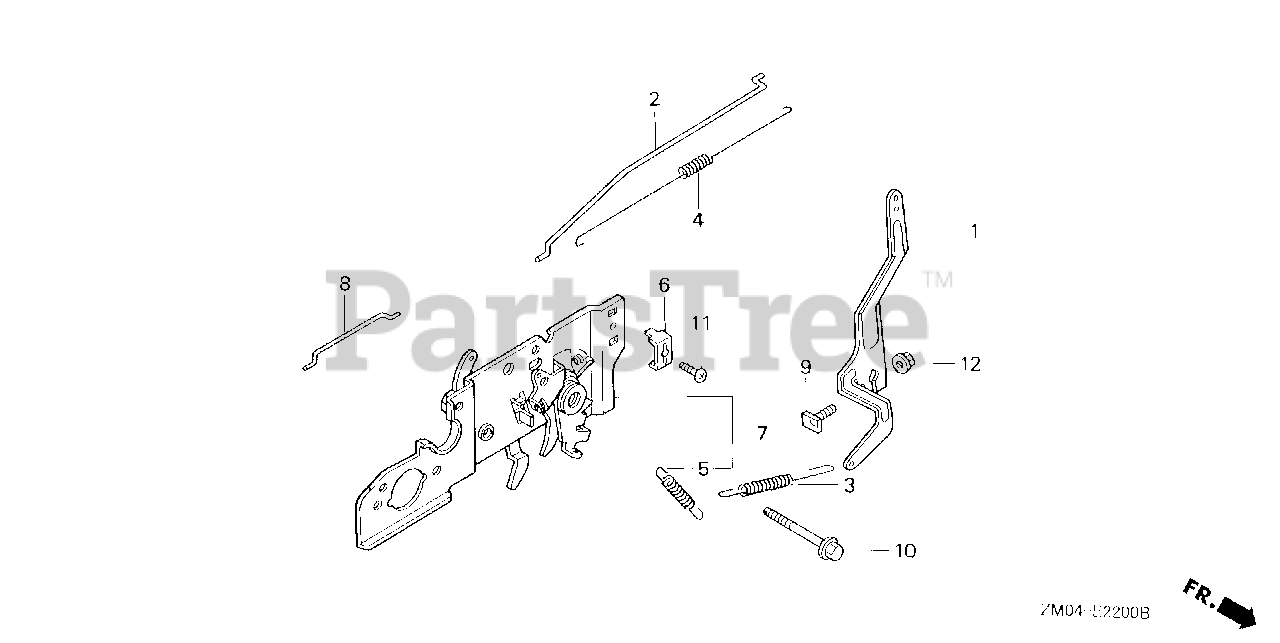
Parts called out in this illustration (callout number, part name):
1	ARM, GOVERNOR
2	ROD, GOVERNOR
3	SPRING, GOVERNOR
4	SPRING, THROTTLE RETURN
5	SPRING, LEVER
6	HOLDER, CABLE
7	BASE, CONTROL
8	ROD, CHOKE
9	BOLT, GOVERNOR ARM
10	BOLT, FLANGE (6X45) (CT200)
11	SCREW, PAN (5X16)
12	NUT, FLANGE (6MM)
